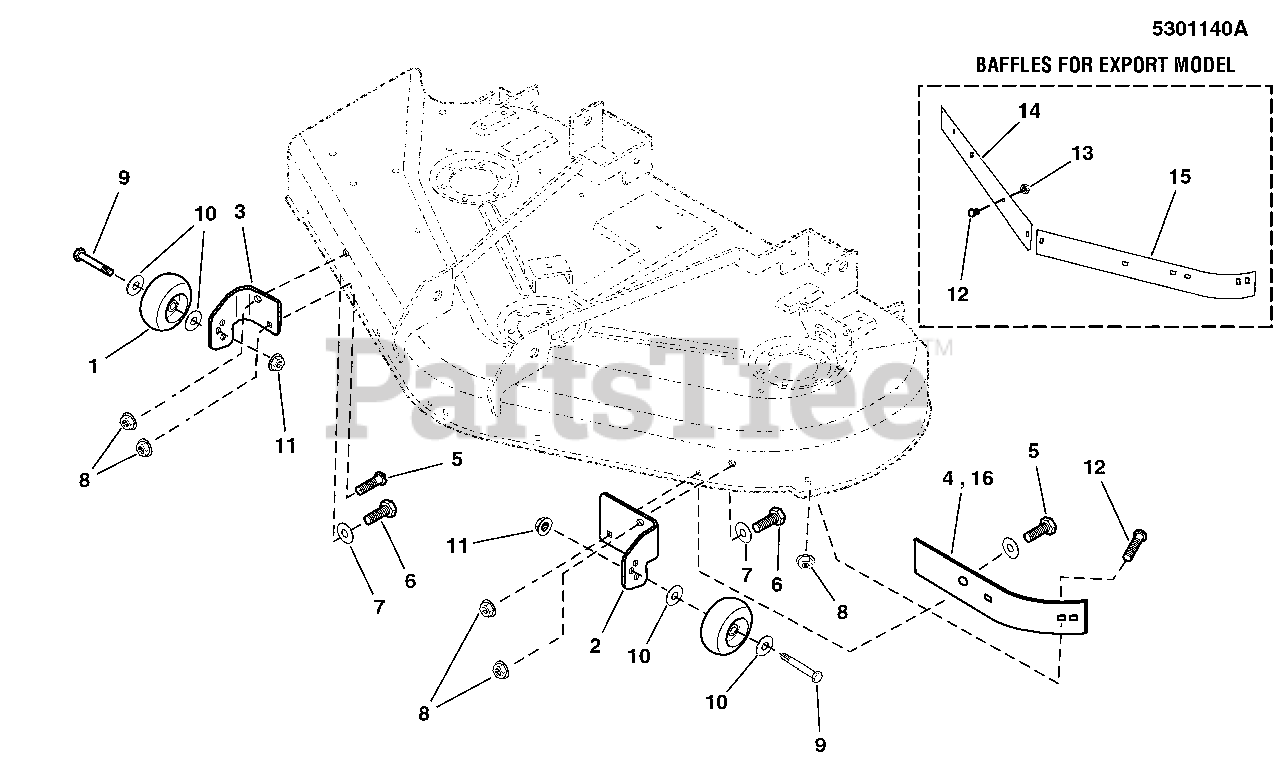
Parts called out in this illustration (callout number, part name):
1	GAUGE WHEEL
2	BRACKET, GAUGE WHEEL, LH
3	BRACKET, GAUGE WHEEL, RH
4	SHORT BLOWOUT BAFFLE BLACK
5	BOLT, 5/16-18 X 1", CARRIAGE
6	CAPSCREW, HEX HEAD,5/16-18 X 1
7	WASHER, 5/16" SAE
8	NUT, 5/16-18 HEX NYLOCK FLANGE
9	BOLT-WHEEL 3/8-16X2.781 .750 THRD YELLOW
10	WASHER-0500(0.51IDX0.87ODX.06THK) BLK
11	NUT, 3/8-16 HEX NYLON FLANGE
12	BOLT, 5/16-18 X 3/4", CARRIAGE
13	NUT, 5/16 - 18 HEX NYLON LOCK
14	BLOWOUT BAFFLE, RH 50" MOWER - BLACK
15	BLOWOUT BAFFLE, LH 50" MOWER - BLACK
16	BAFFLE FRONT 44, 50 MOWERS
